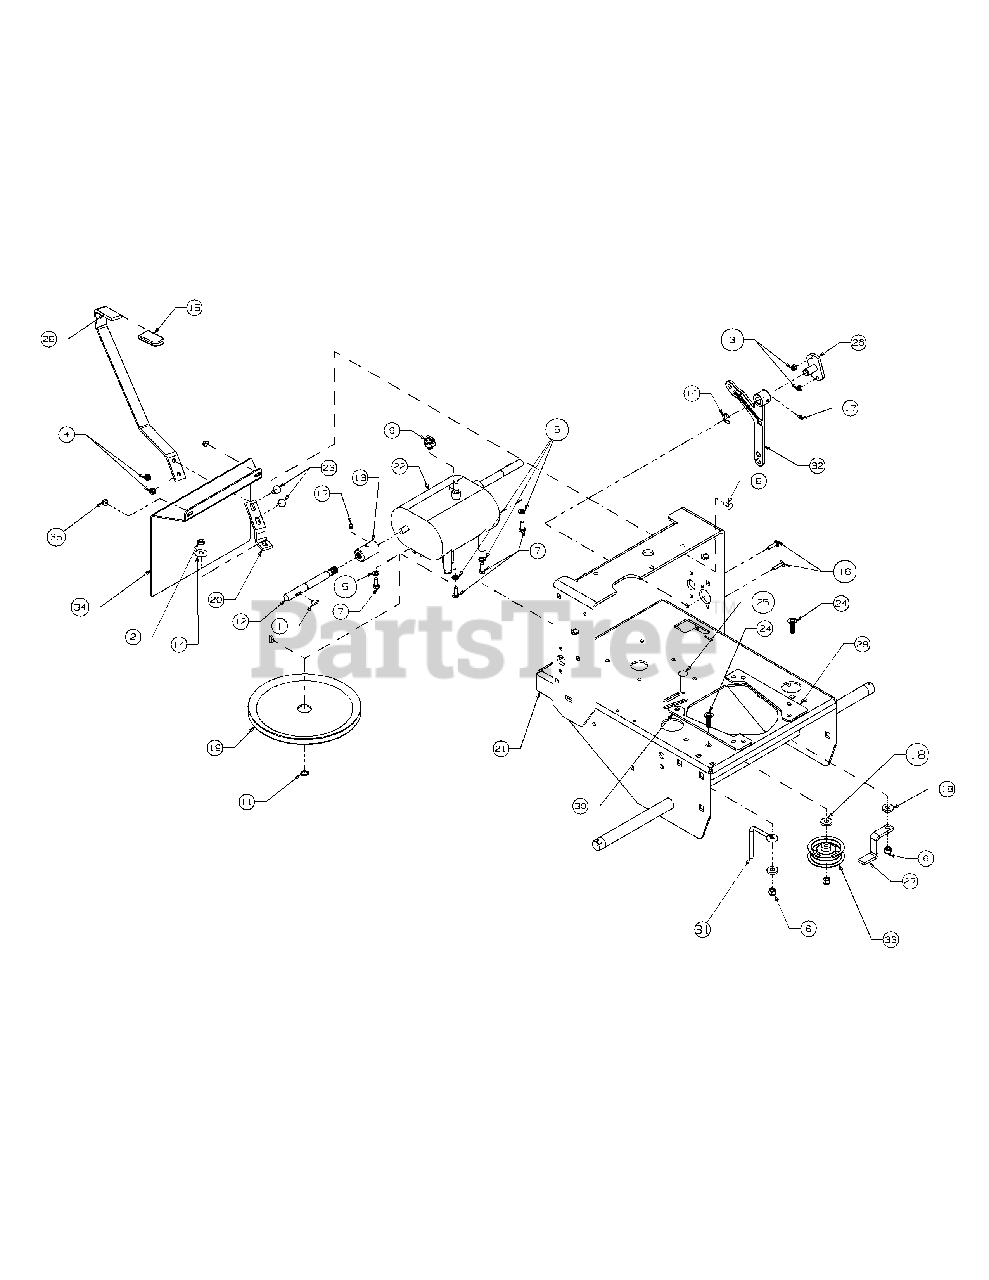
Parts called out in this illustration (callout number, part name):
1	Woodruff Key, 3/16 x 3/4
2	Jam Nut, Insert Lock, 3/8-24
3	Lock Nut, Nylon Insert, 1/4-20
4	Nut, 5/16-18 Nylock
5	Lock Washer, 5/16 Zinc
6	Lock Nut, Nylon Insert, 3/8-16
7	Hex Cap Screw, 5/16-18 x 3/4
8	Carriage Bolt, 1/4-20 x .750
9	Switch, WB Transmission
10	E-Ring, 5/8
11	External Retainer Ring
12	Jackshaft w/ Heavy Spline
13	Coupling w/Heavy Spline
14	Bell Washer, .39 ID x 1.13 OD x .062
15	Grip, .250 x 1 x 3-1/2, Yellow
16	Carriage Bolt, 1/4-20 x 1.00
17	Grease Fitting, 1/4-28 x 3/16
18	Idler Washer
19	Transmission Pulley
20	Shift Arm
23	Carriage Bolt, 5/16-18 x 1
24	Carriage Bolt, 3/8 -16 x 1.25
25	Carriage Bolt, 3/8-16 x2
26	Bellecrank Pivot, Weldment
32	Clutch, Bellecrank Casting
33	Flat Idler Pulley w/Adapter
